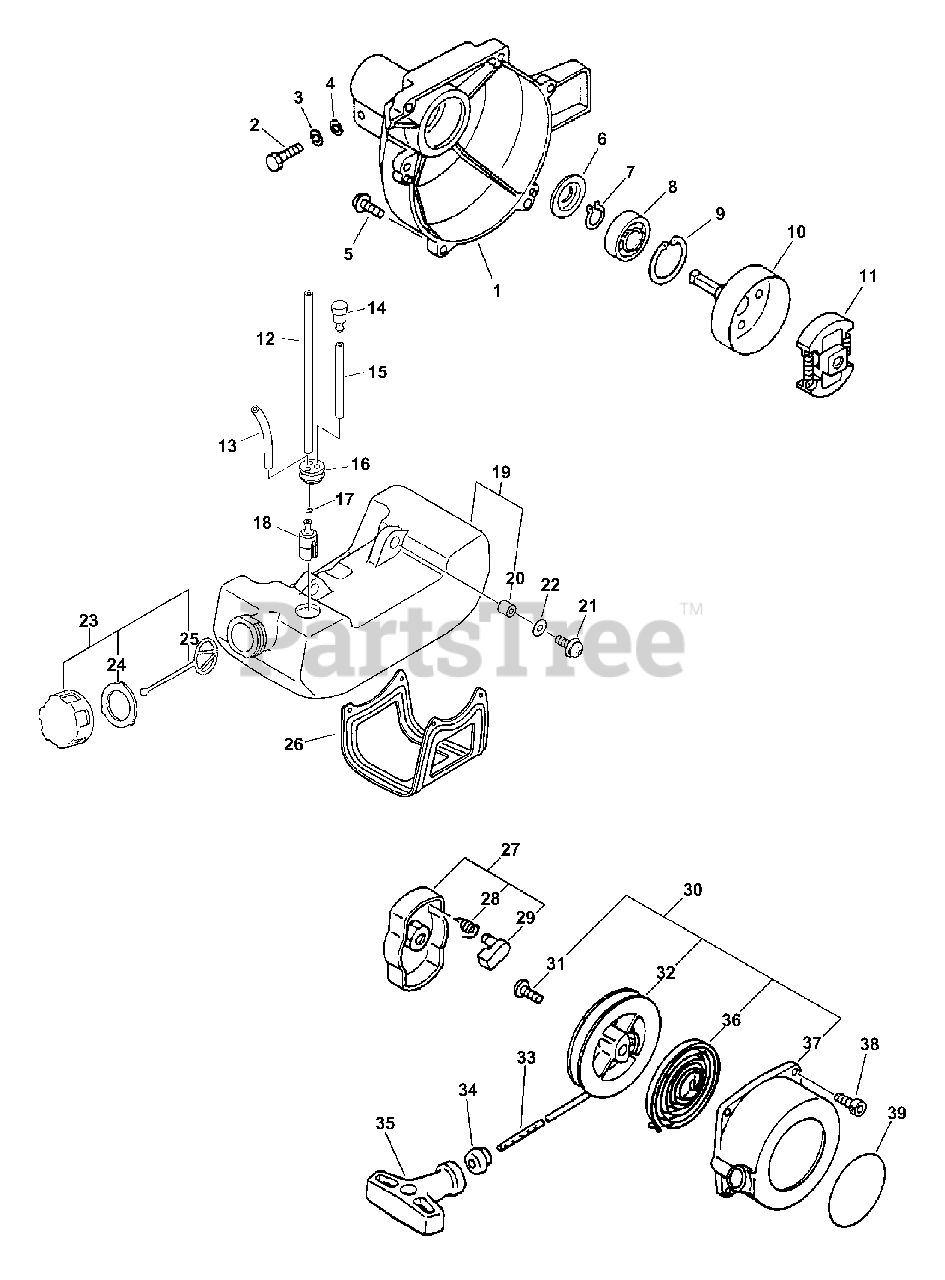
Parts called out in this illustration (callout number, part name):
1	CASE, FAN
2	BOLT 5×25
3	WASHER, SPRING 5
4	WASHER, FLAT 5.5×10×0.8
5	BOLT 4×16
6	STOPPER, PIPE
7	RING, RETAINING - 12
8	BEARING, BALL 6201-ZZ
9	RING, SNAP Ø32
10	DRUM, CLUTCH
11	CLUTCH ASSY
12	PIPE, FUEL 3x-5x-180
13	PIPE, FUEL RETURN 3×6×90 MM CLEAR
14	VENT ASSY
15	PIPE, FUEL 3x-5x-70 BLACK
16	GROMMET, FUEL
17	CLIP 6 MM
18	FILTER, FUEL
19	TANK, FUEL
20	SPACER 6.2×7.8×6
21	SCREW 5×16
22	WASHER 5.5×12×0.8
23	CAP ASSY, FUEL
24	GASKET, FUEL CAP
25	CONNECTOR, CAP
26	GUARD, FUEL TANK
27	PAWL ASSY, STARTER
28	SPRING, RETURN
29	PAWL, STARTER - BLACK
30	STARTER ASSY, RECOIL
31	SCREW
32	REEL, ROPE
33	ROPE, STARTER 3.0×1000
34	GUIDE, ROPE
35	GRIP, STARTER
36	SPRING, RECOIL
37	CASE, RECOIL STARTER
38	BOLT 4×16
39	LABEL, ECHO
